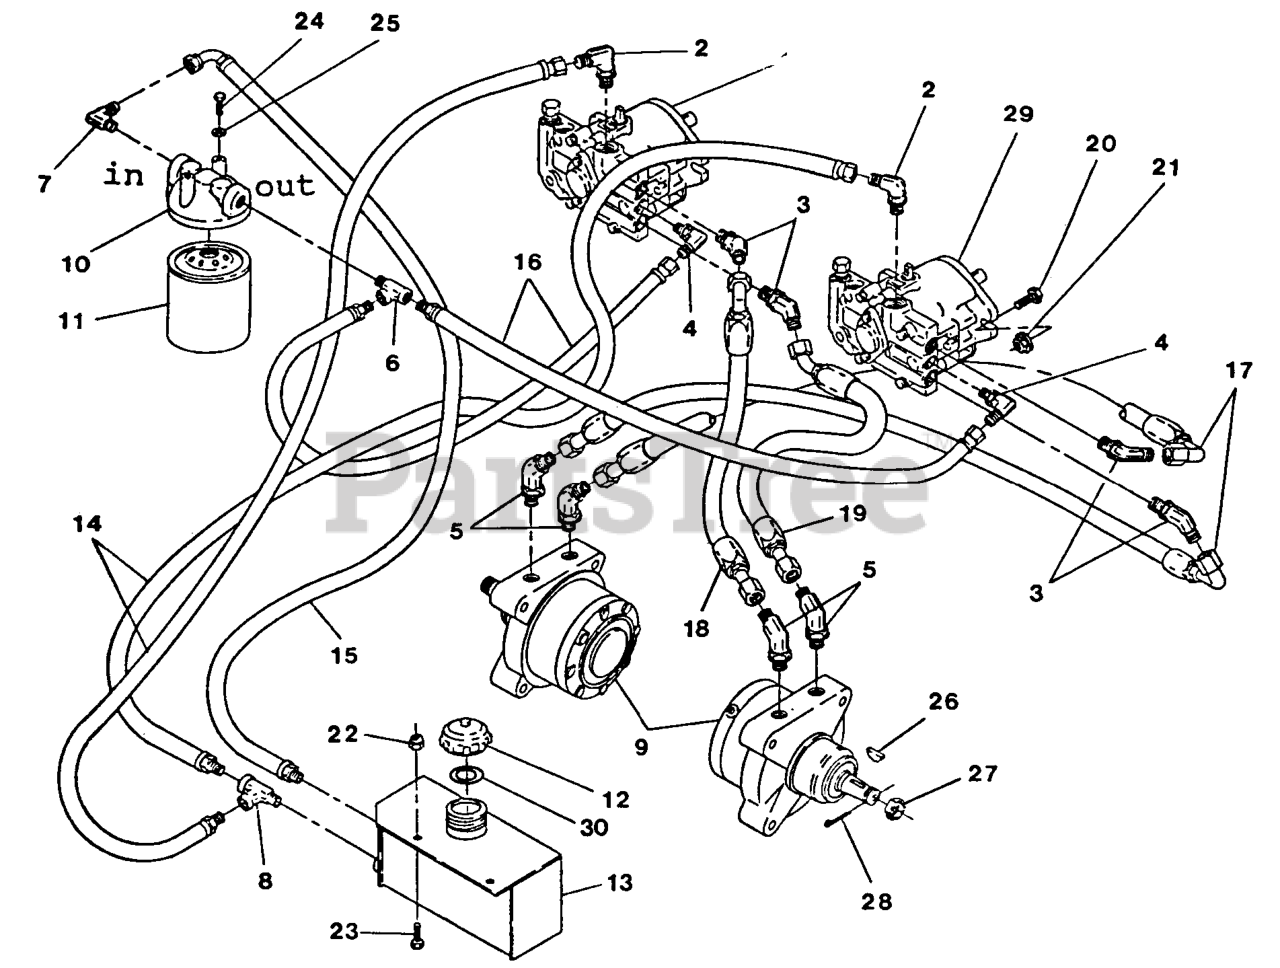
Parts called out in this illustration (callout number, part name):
2	FITTING-90 DEG
4	ELBOW,90 DEGREE
5	FITTING,45 DEGREE
10	FILTER-HEAD
25	WASHER-LOCK
28	PIN-COTTER
30	GASKET-CAP, TANK
